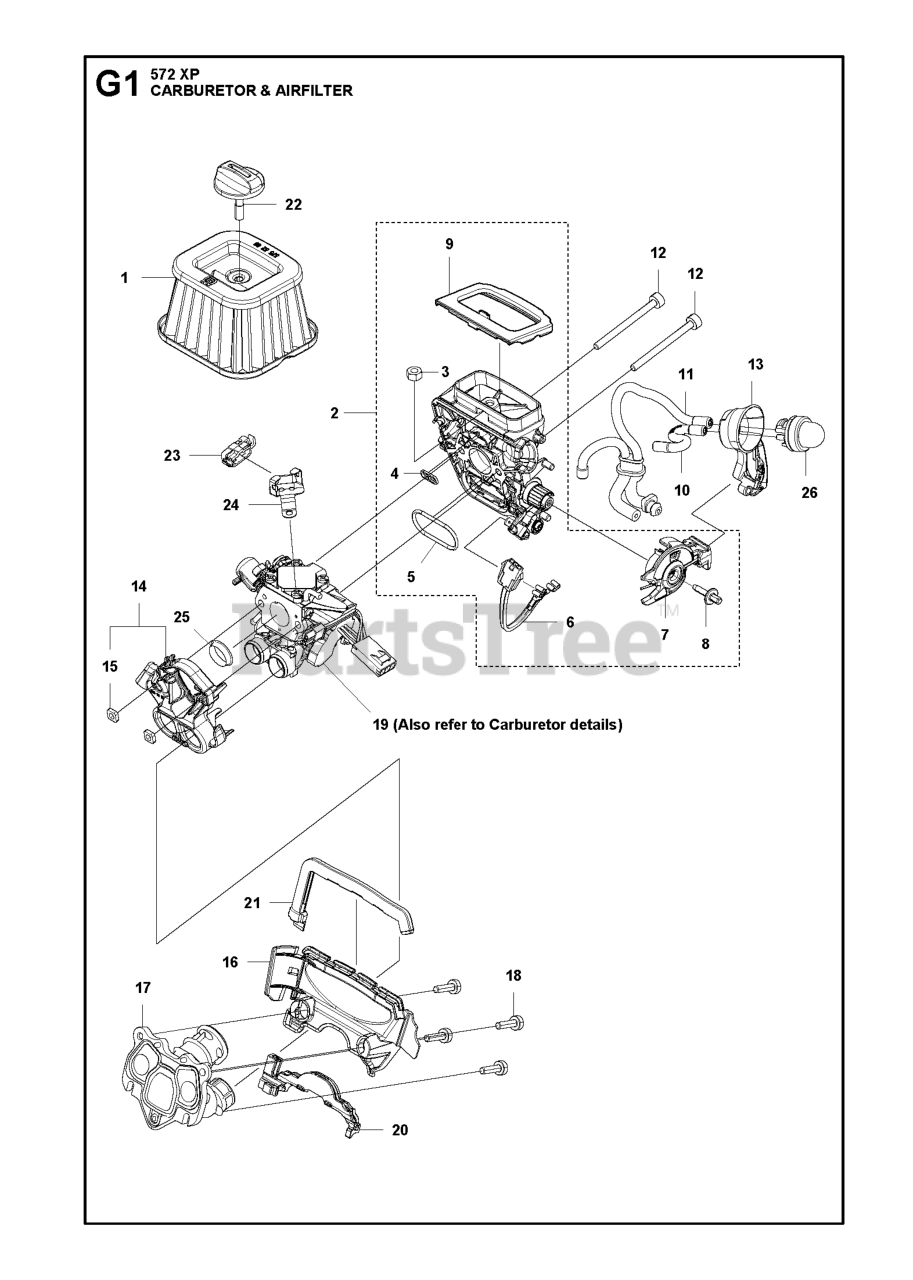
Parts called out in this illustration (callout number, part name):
1	AIR FILTER ASSY H572 HD NW
1	AIR FILTER ASSY H572 HD 25 MIC
1	AIR FILTER ASSY H572 HD 64 MIC
2	INLET ELBOW STANDARD SPARE PAR
2	INLET ELBOW HEATED SPARE PART
6	WIRING ASSY STOP
7	CHOKE CONTROL ASSY CHOKE/STOP
9	SEALING FILTER HOLDER
11	FUEL HOSE PURGE/TANKVENTILATIO
12	SCREW ITXSCFM M4X50 T20 12.9
14	FLANGE CARBURETTOR FLANGE
16	BAFFLE INTERMEDIATE WALL INTER
17	INLET PIPE H565/H572 STD
17	INLET PIPE H565/H572 COLD
18	SCREW ITXSCM M4X15 T27 12.9 T
19	CARBURETTOR KIT 572XP
20	SEALING INLET PIPE
21	SEALING BAFFLE
22	HANDLE AIR FILTER COVER
23	CONTACT CLAMP
24	RETAINER CONTACT CLAMP
25	SUPPORT SLEEVE
26	AIR PURGE BUBBLE
